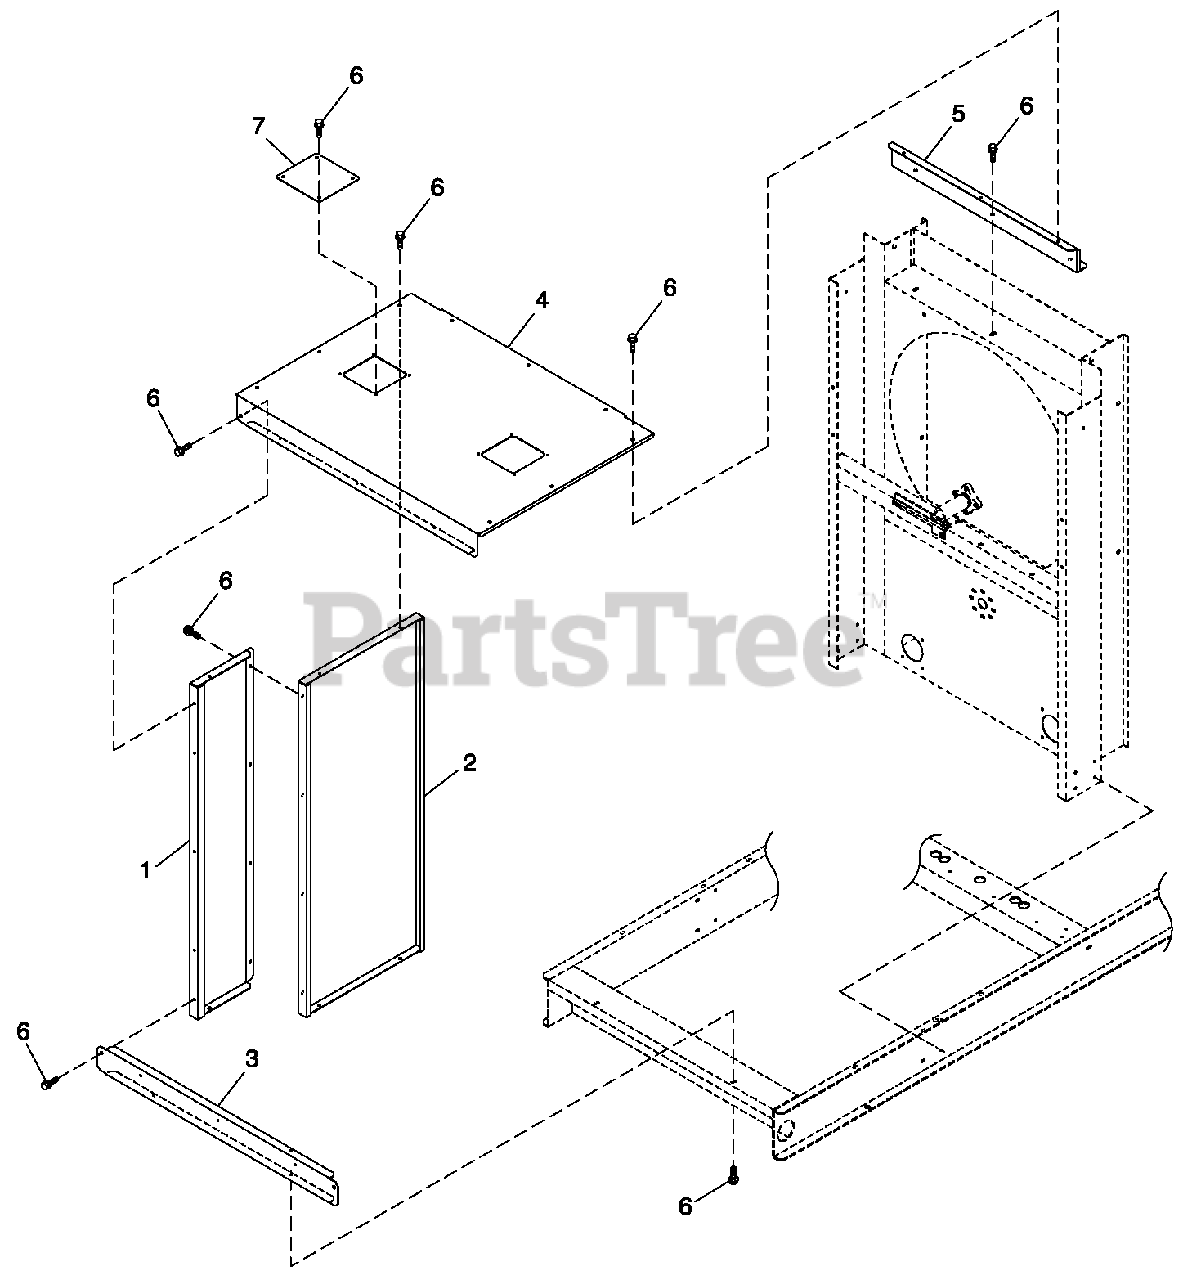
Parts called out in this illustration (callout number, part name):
1	PANEL C5 FRONT SIDES
2	PANEL C5 REAR SIDES
3	PANEL LOWER FRONT
4	PANEL C5TOP
5	PANEL C5TOP MOUNT
6	SCREW THF M6-1 X 16 N WA Z/JS
7	ACCESS COVER 160 X 170 GALV
